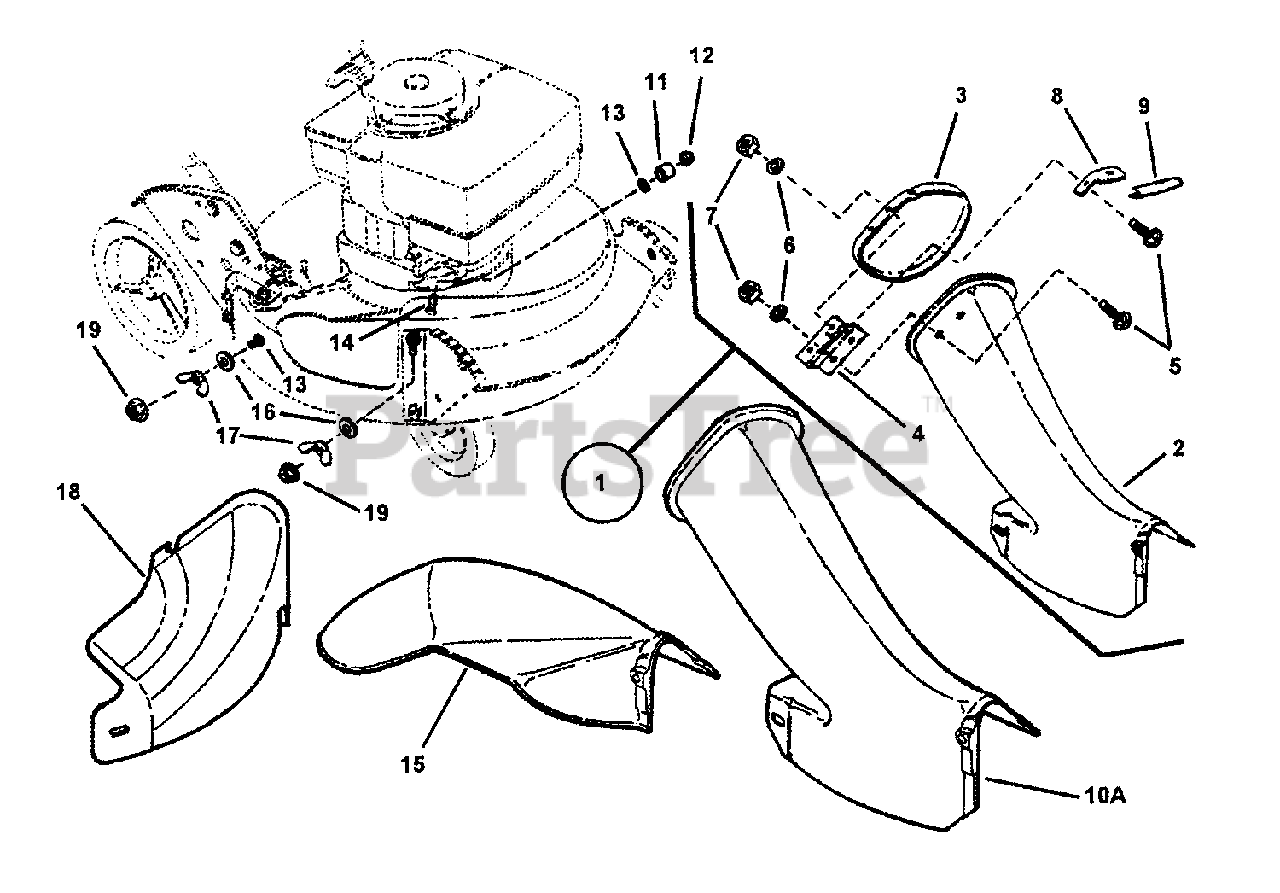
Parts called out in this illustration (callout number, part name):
1	ASSY, Bag Adapter & Cover (Incl 8 items below)
2	ADAPTER, Grass Bag
3	COVER, Bag Adapter
4	HINGE, Chute Cover
5	BOLT, 1/4-20 x 1/2" Short Neck Carriage GR5
6	WASHER, 1/4" Internal Tooth Lock
7	NUT, 1/4-20 Hex
8	STOP, Cover
9	MOLDING, Trim
10A	ADAPTER, Grass Bag
10A	ASSEMBLY, Grass Bag Adapter (Includes Rope Pulley shown in Grass Bag Group)
11	SPACER, .316 I.D. x .375 O.D. x .310 thick
12	NUT, 5/16-18 Hex Large Flange Center Lock
13	RETAINER, 5/16" Bolt
14	BOLT, 5/16-18 x 3/4" Short Neck Carriage GR5
15	CHUTE, Side
16	WASHER, 3/8" Flat
17	WING-NUT, 5/16-18 Nyloc
18	COVER, 21" Deck
19	NUT, 5/16-18 Hex Large Flange Center Lock
